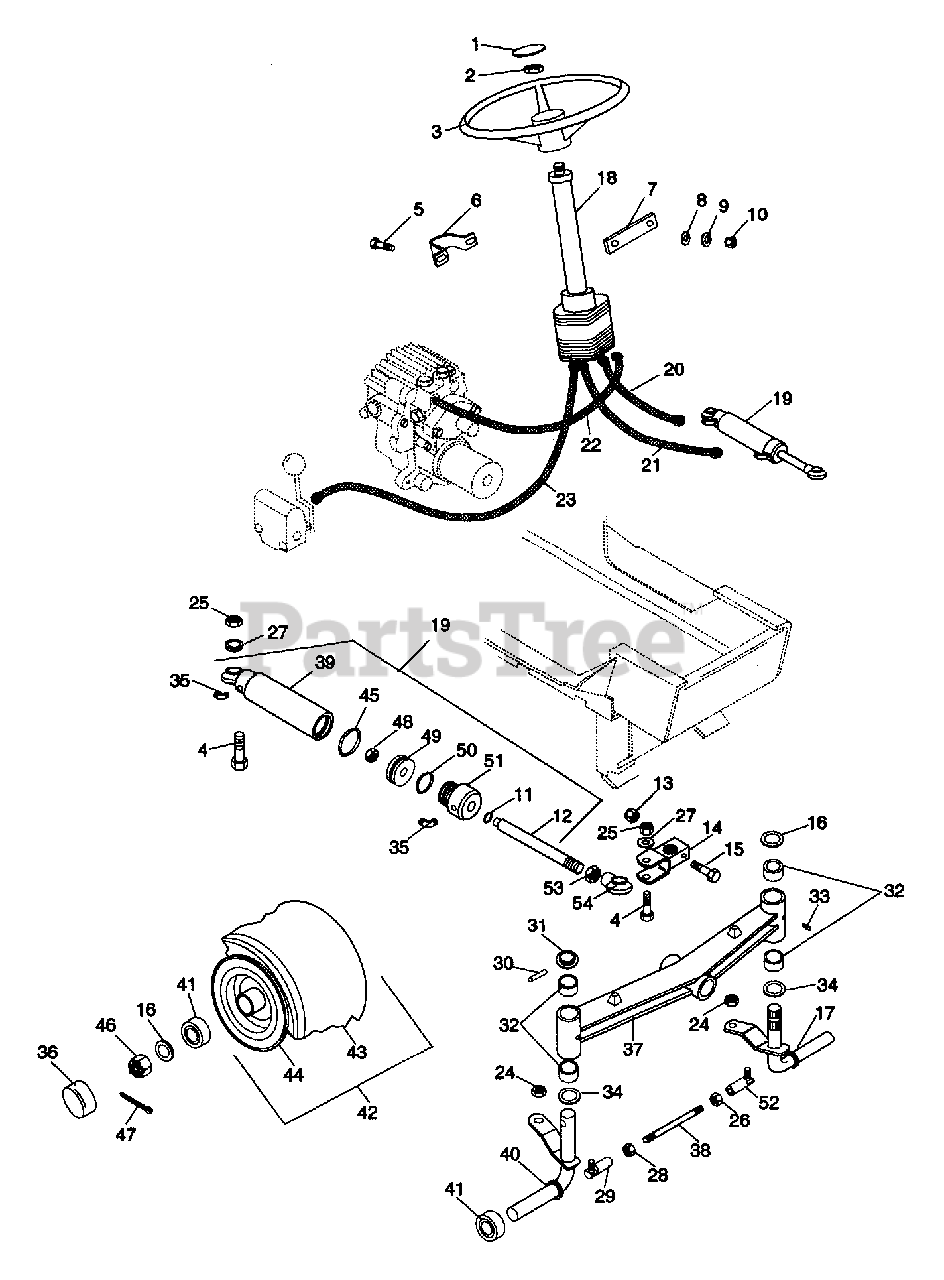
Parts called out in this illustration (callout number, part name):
1	DOME PLUG
2	NUT-LK-JAM .625-18 YWZC
3	STEERING WHEEL
4	BLT-HEX .62-18X2.00 GR5
5	BLT-RDHDSQNK .31-18X1.0 SHT PL
6	STEERING COLUMN CLAMP
8	WSHR-FL-STL .38X.875X.083 PL
9	WSHR-LK .312X.097 PL HVY
10	NUT-HEX .312-18
11	O-RING .609X.609X.139
12	ROD
13	NUT-LK-CROWN .50-13 GR C PL
14	STEERING ARM
15	LOCK BOLT
16	WSHR-FL-STL 1.015X1.500X.125
17	SPINDLE LH
18	STEERING UNIT
19	CYLINDER ASSEMBLY (SHORT)
20	HYDRAULIC HOSE
21	HYDRAULIC HOSE
22	HYDRAULIC HOSE
23	HYDRAULIC HOSE
24	NUT-LK .50-20 PL
25	NUT-LK-JAM .625-18 YWZC
26	NUT-JAM-SL 1.0-14
27	WSHR-FL-STL .630X1.005X.062 PL
28	NUT-JAM .50-20 PL
29	BALL JOINT R.H.
30	PIN-ROLL .250X1.75
31	SPINDLE CAP
32	BSHG-SLV 1.000X1.125X.875
33	SPIN DRIVE ZERK FITTING
34	PLASTIC WASHER
35	ADAPTER 45 9/16 TO 1/4
36	FRONT HUB CAP
37	FRONT AXLE ASSY
38	TIE ROD
39	CYLINDER
40	SPINDLE RH
41	BRG-BALL 1.0X2.0X.55
42	T/WHL ASSY
43	TIRE 16X6.50-8 2 PLY
45	O-RING 1.625X2.000
46	NUT-SL 1.0-14
47	PIN-COTR .18X1.25 PL
48	NUT-LK .375-24 PL
49	PISTON
50	O-RING 1.937X2.125
51	ROD CAP
52	BALL JOINT L.H.
53	NUT-JAM .625-11 PL
54	BALL END
